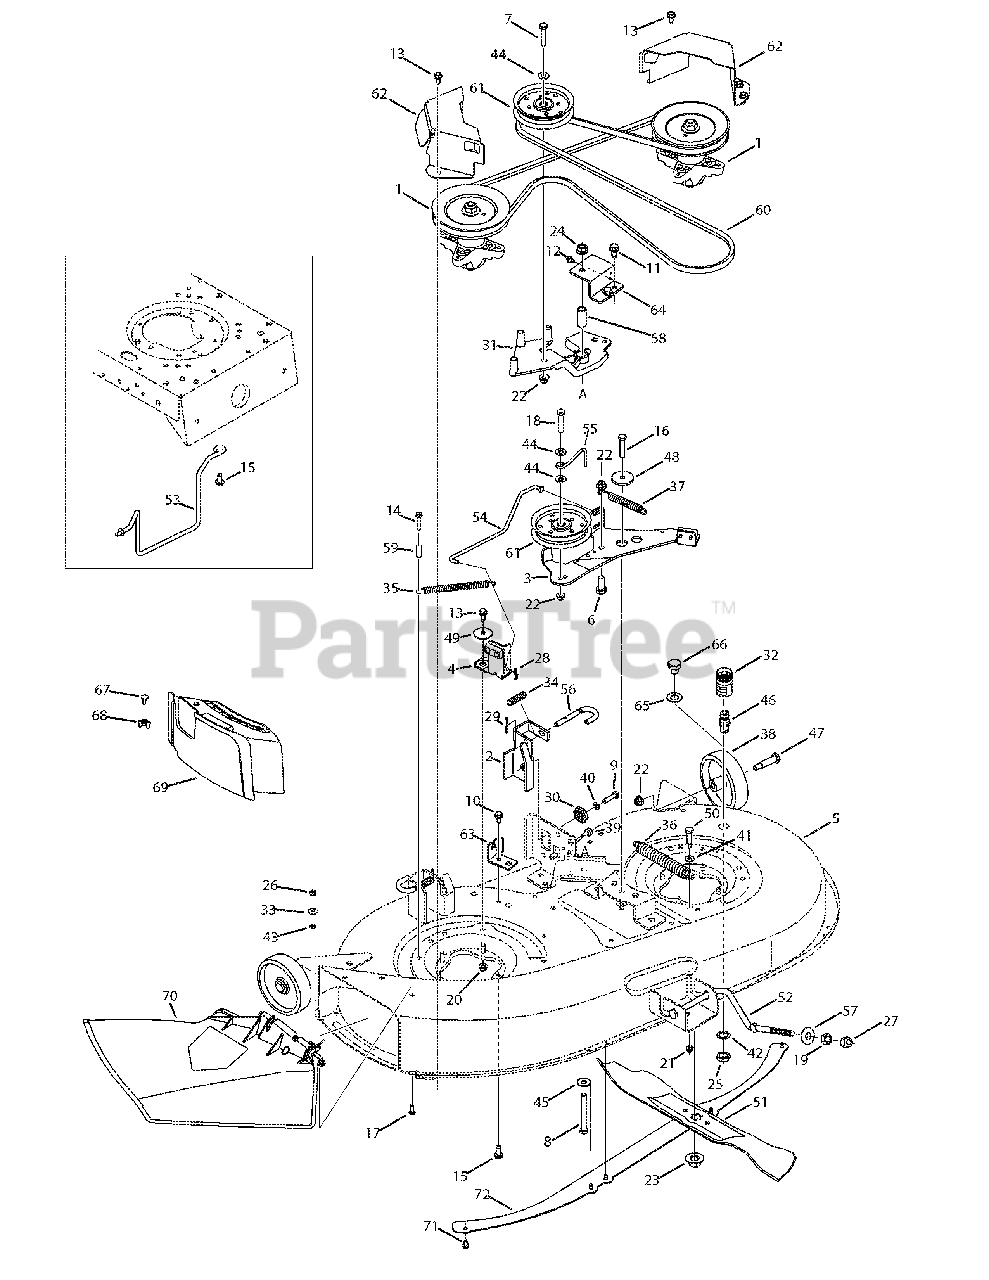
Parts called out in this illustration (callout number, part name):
1	Spindle Assembly Pulley 6.3 Dia
2	Deck Hanger Bracket Assy. LH
3	Brake Assembly, 42" Deck
4	Brake Assembly, 42" Deck
5	Deck Assembly 42" W/Whl Brkt.
6	Screw, 3/8-16 x .75 GR5 STD
7	Screw, 3/8-16 x 1.75 GR5 STD
8	Screw, 7/16-20 x 3.00 GR5 STD
9	Screw, 5/16-18 x 1.25 GR5 STD
10	Screw, 5/16-18 x 0.75
11	Screw, 3/8-16 x 0.750
12	Screw, 1/4-20 x 0.375
13	Screw, 5/16-18 x 0.750
14	Screw, 1/4-20 x 1.500
15	Screw, 5/16-18 x 0.750
16	Screw, 3/8-16 x 1.25
17	Screw, 1/4-20 x .75
18	Screw, 3/8-16 x 2.00
19	Hex Nut, 1/2-13
20	Flange Lock Nut, 5/16-18
21	Flange Lock Nut, 1/4-20
22	Flange Lock Nut, 3/8-16
23	Flange Nut, 5/8-18
24	Flange Lock Nut, 7/16-20
25	Hex Nut, M16-1.5 DIN 936
26	Hex Nut, 1/4-20
27	Hex Lock Nut, 1/2-13
28	Cotter Pin, .072 Dia. x 1.13 Lg.
29	Cotter Pin, 1/8 x 1.25
30	Deck Gear Adjustment
31	Idler Bracket, Cast 42" DECK
32	Water Nozzle Adapter
33	Push Nut, .25 ID x .50 OD
34	Compression Spring .531 x 1.75
35	Extension Spring, .500 x 6.375
36	Extension Spring, .94 x 6.74
37	Extension Spring, .53 x 4.75
38	Deck Wheel, 5.0 x 1.38
39	Bumper, .62 Dia. x .3
40	Lock Washer, 5/16
41	Flat Washer, .28 x .74 x .063
42	Lock Washer, 5/8
43	Bell Washer, .265 x.75 x .062
44	Flat Washer, .406 x .875 x .059
45	Flat Washer, .450 x 1.250 x .164
46	Deck Water Nozzle
47	Shoulder Bolt, .496 x 1.525
48	Shoulder Spacer, .8840 x .190
49	Shoulder Spacer, .5000 X .1475
50	Shoulder Screw, .374 x 1.16
51	3 in 1 Star Blade 21.23"LG
52	Adjustible Front Deck Rod,
53	Belt-Keeper Rod, 42"
54	Brake Control Ride, 42"
55	Belt Keeper Rod, 42" IDLER
56	Deck Release Handle Rod
57	Deck Lift Pivot Cup
58	Spacer, .455 X .697 X 1.585
59	Spacer, .260 x .372 x 1.030
61	Idler Pulley, 4.25"DIA
62	Belt Covers, 6.00 DIA
63	Cable Deck Engage Bracket
64	Support Bracket
65	Flat Washer, .64 x 1.24 x .06
66	Bolt Plug, M16 x 1.5
67	Carriage Screw, 1/4-20 x .62
68	Wing Nut, 1/4-20
69	Mulch Plug
70	Discharge Chute Assembly
71	Screw, Hex, 1/4-20, 0.500
